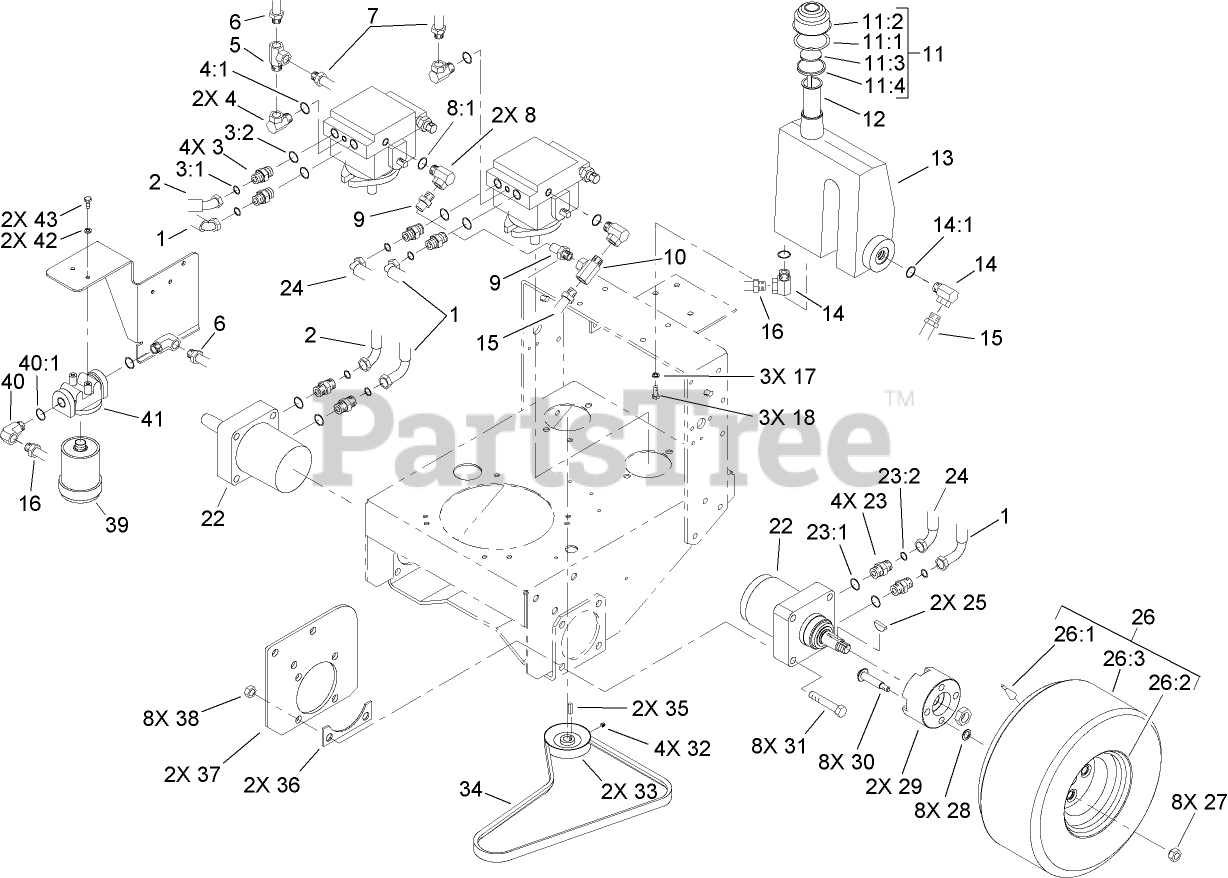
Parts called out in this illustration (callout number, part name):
1	HYD HOSE ASM
2	HYD HOSE ASM
3	FITTING-STRAIGHT
3:1	O-RING
3:2	O-RING
4	SWIVEL-PIPE, FEMALE
4:1	O-RING
5	FITTING-HYD, TEE
6	HYD HOSE ASM
7	HYD HOSE ASM
8	FITTING-HYD, 90 DEG
8:1	O-RING
9	HYD HOSE ASM
10	FITTING-HYD, TEE
11	OIL CAP ASM
11:1	O-RING
11:2	CAP-OIL
11:3	FOAM-FILTER, OIL CAP
11:4	DIPSTICK
12	SCREEN-FILLER
13	RESERVOIR-OIL
14	FITTING-HYD, 90 DEG
14:1	O-RING
15	HYD HOSE ASM
16	HYD HOSE ASM
17	WASHER-LOCK
18	SCREW-HH
22	WHEEL MOTOR ASM
23	FITTING-STRAIGHT
23:1	O-RING
23:2	O-RING
24	HYD HOSE ASM
25	KEY-WOODRUFF
26	WHEEL AND TIRE ASM
26:1	STEM-VALVE
26:2	WHEEL
27	NUT-LUG
28	PUSHNUT
29	HUB-WHEEL
30	SCREW-HH
31	SCREW-HH
32	SCREW-SET
33	PULLEY-PUMP
34	BELT-V
35	KEY-PUMP
36	SPACER-FRAME
37	PLATE-FRAME
38	NUT-LOCK, NI
39	CARTRIDGE-FILTER, OIL
40	FITTING-HYD, 90 DEG
40:1	O-RING
41	HEAD-FILTER
42	WASHER-LOCK
43	SCREW-HH
